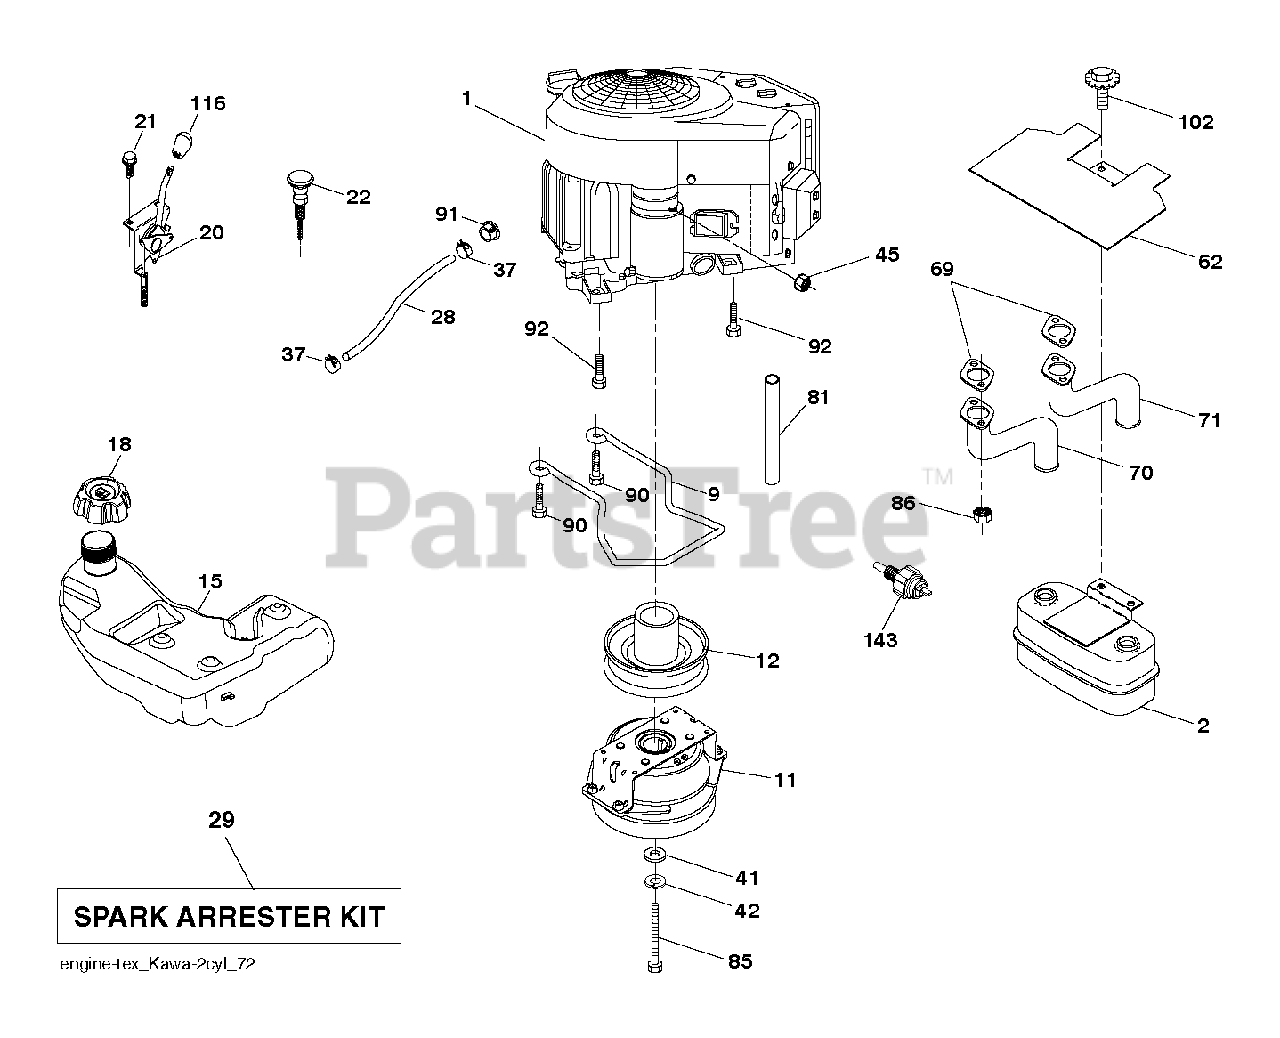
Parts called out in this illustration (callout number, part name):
2	Muffler Assembly, Twin MN
9	KEEPER.BELT.ENG.4.25"2.BLT.431
11	CLUTCH.OGURA.5.0PD.GT1.5A-EH01
12	PULLEY ENGINE
15	TANK SUBASM; 4 GAL MFG YEAR 20
18	CAP ASSY FUEL 3" GRAY
20	CONTROL.THROTTLE.PRO.
21	SCREW.#10 X 0.750.BOS
22	CONTROL, CHOKE
28	HOSE.1/4".LOW.PERM.FUEL.LN.60"
29	KIT.SPARK ARRESTOR 794945 B&S
37	HOSE CLAMP
42	WASHER 7/16 LOCK
45	NUT
62	SHIELD.HEAT.MUFFLER
70	TUBE.EXHAUST.LH.FR961/FR730
71	TUBE.EXHAUST.RH.FR961/FR730
81	TUBE, DRAIN OIL ASM.
85	BOLT.HEX.7/16-20X3.GR5.YELLOW
86	NUT.HEX.FLANGE.TOPLOCK
90	SCREW 3/8-16X1
91	BUSHING.1.375OD
92	SCREW 3/8-16X1
102	SCREW
116	KNOB - SHIFT
143	SENSOR.SWITCH.PRESSURE.OIL
